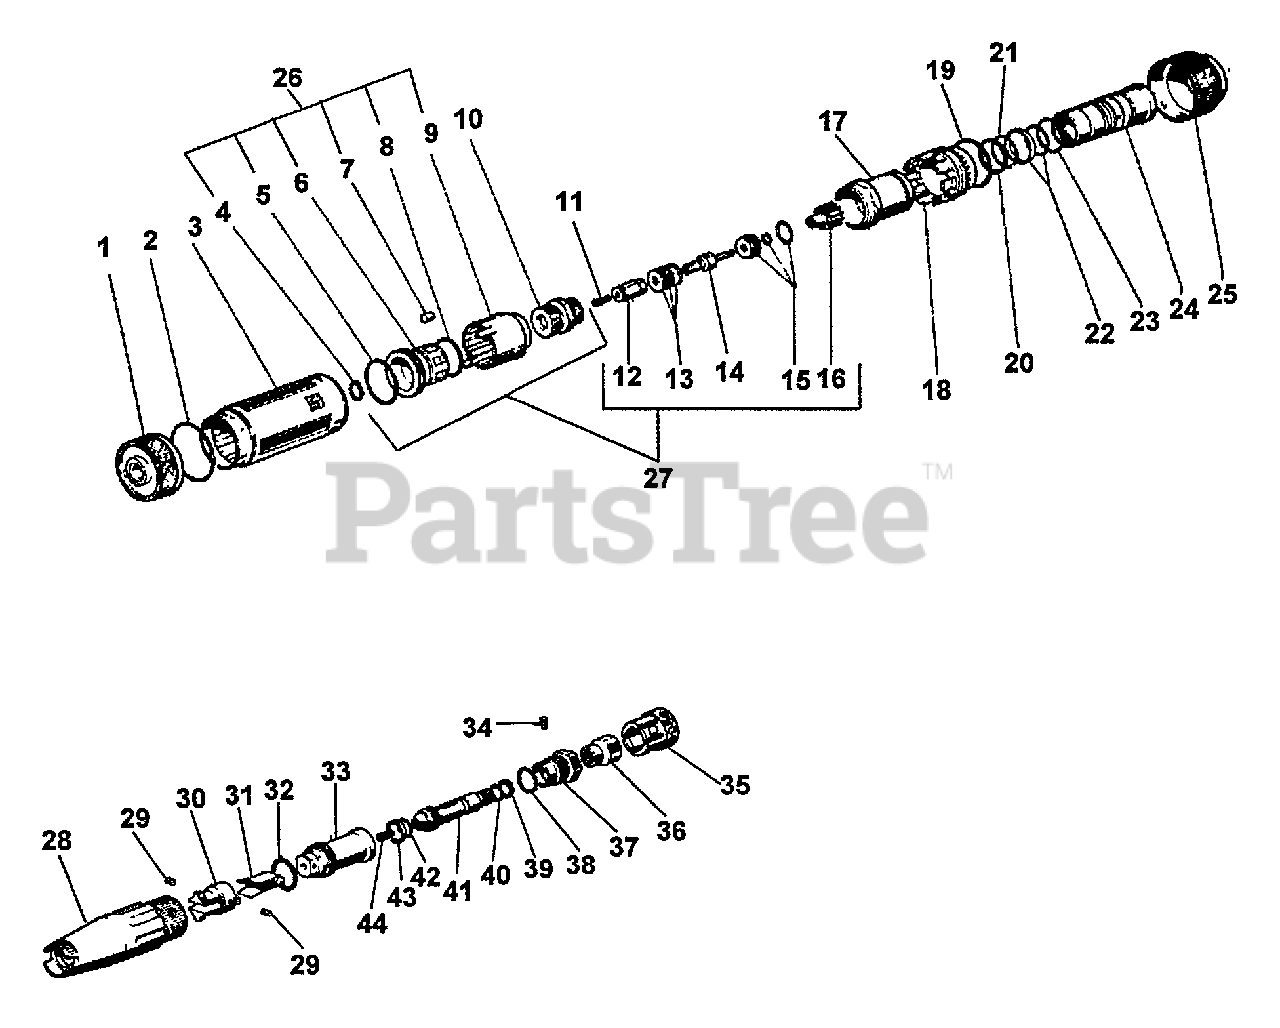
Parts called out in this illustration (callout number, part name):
1	CAP, FRONT
2	O-RING
3	KNOB, ADJUSTMENT
4	RING, RETAINING
5	O-RING
6	ROTOR
7	BEARING, ROLLER
8	O-RING - .797 X.103
9	CLUTCH
10	RINGNUT
11	NOZZLE - RED
12	HOLDER, NOZZLE
13	BEARING, BALL
14	CRANKSHAFT ASSY
15	SEAL ASSY
16	ROTOR
17	CYLINDER, DIFFUSER
18	DIFFUSER, LOW PRESSURE
19	O-RING
20	RING, ANTI-EXTRUSION
21	O-RING
22	SEAL, RING
24	BODY, DIFFUSER
25	RING, LOCK
26	KIT, (PARTIAL) ROTOX REBUILD
27	ROTOX REBUILD KIT
28	KNOB, REGULATING
29	PIN
30	HOLDER, BLADE
32	O-RING
33	CYLINDER
34	SCREW
35	KNOB, REGULATING
36	COUPLING
37	NUT, ADJUSTING
38	O-RING
39	RING, SEALING
41	TUBE
42	O-RING
43	SPACER
44	NOZZLE - RED
